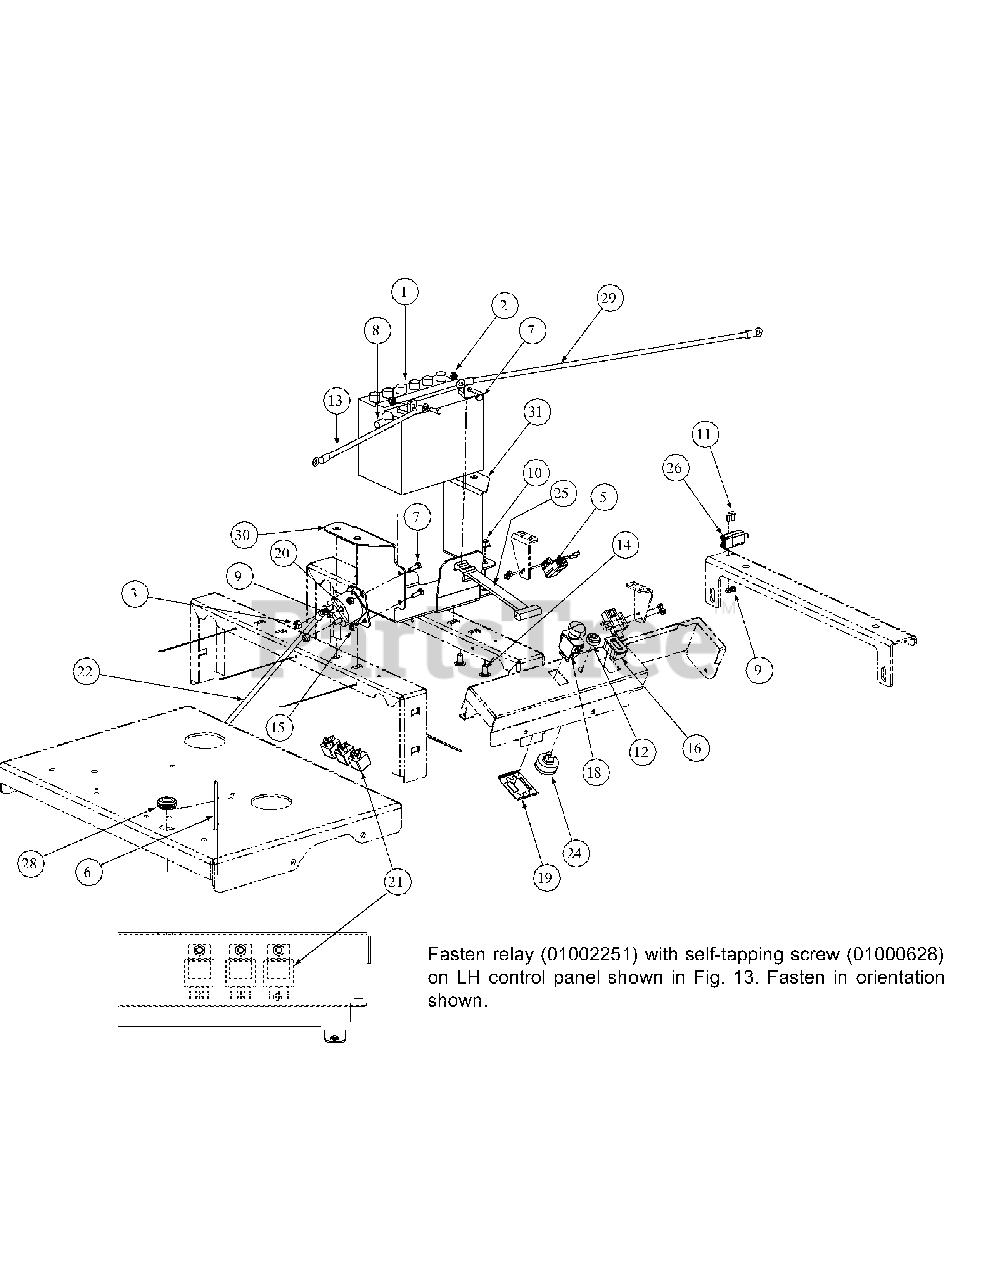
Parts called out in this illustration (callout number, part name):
1	Battery, 12V 225CCA 30 Min
2	Hex Flange Lock Nut, 1/4-20
3	Nylock Nut, 5/16-18
5	Switch, Safety N.O.\N.C.
6	Tie, Cable, 3/16 x .05 x 7.4"
7	Screw, Hex, Cap, 1/4-20 x .75
8	Boot, 1" OD Rubber Battery-PST, Red
9	Nut, Lock, Nylon Insert, #10-32
10	Nut, Hex, Flange Lock, 3/8-16
11	Screw, Phillips Head, Machine, 10-32 x 5/8
12	Nut, W/Cap, 5/8-32 Ignition
13	Cable, Battery, Red, 15"
14	Carriage Bolt, 3/8-16 x .75 LG.
15	Lock Nut w/Nylon Insert
16	Meter, Hour
17	Hourmeter, Harness
18	Switch, Electric, PTO
19	Bracket, PTO Switch Retainer
20	Solenoid Magnetic Switch
21	Relay, 12V 40A
22	Cable, Battery Red, 32"
24	Switch, Ignition, 6 Pin
25	Strap, Battery
26	Switch, Plunger N.O.\N.O.
27	Harness Assembly
28	Grommet, .75 ID
29	Cable, Battery Black, 28"
30	Mount Bracket, Battery
31	Mount Bracket, Battery
